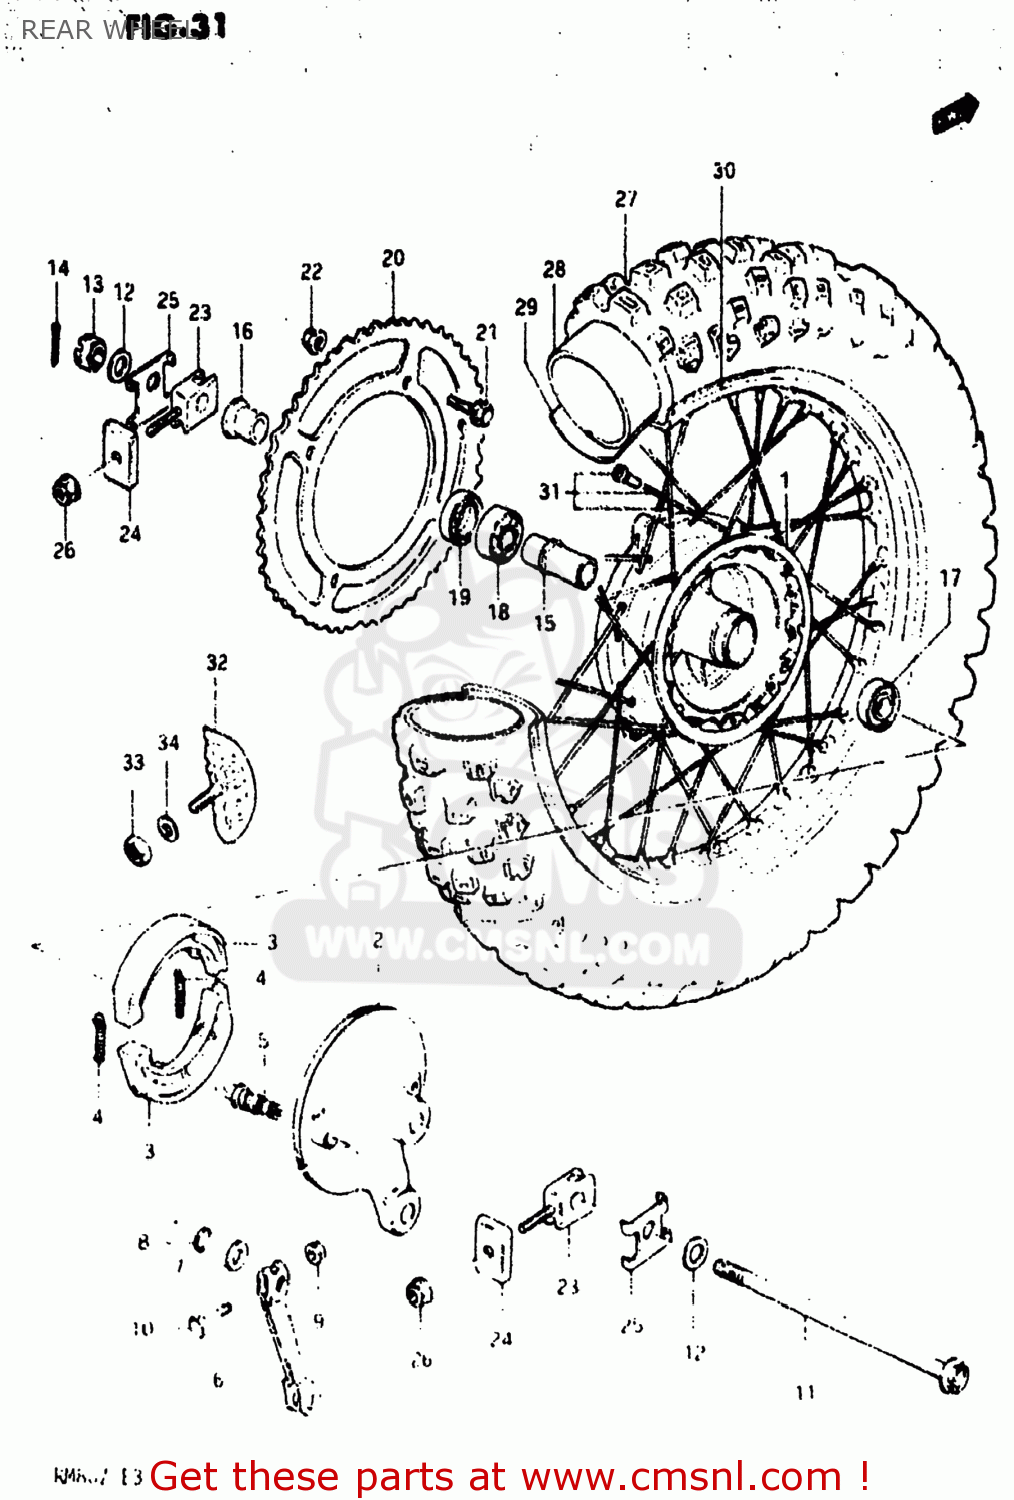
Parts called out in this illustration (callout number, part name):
1	HUB,REAR
2	PANEL,REAR HUB
3	SHOE,BRAKE
4	SPRING(L:34)
5	CAM,FRONT BRAKE
6	LEVER,RR BRAKE CAM
7	WASHER(12.5X20X1)
8	O RING(D:2.5,ID:11.4)
9	NUT
10	BOLT
11	AXLE,REAR
12	WASHER
13	NUT 12MM
14	PIN 30X20
15	SPACER,REAR HUB BEARING
16	SPACER,RR AXLE,L
17	BEARING
18	BEARING
19	OIL SEAL(17X38X5)
20	SPROCKET,REAR
21	BOLT(8X31)
22	NUT
23	ADJUSTER,CHAIN
24	ADJUSTER,CHAIN
25	WASHER,CHAIN ADJUSTER
26	NUT
27	TIRE
28	TUBE ASSEMBLY,WHEEL,INNER
29	PROTECTOR,INNER TUBE
30	RIM,REAR WHEEL
31	SPOKE SET,REAR WHEEL
32	STOPPER,BEAD
33	NUT
34	WASHER
